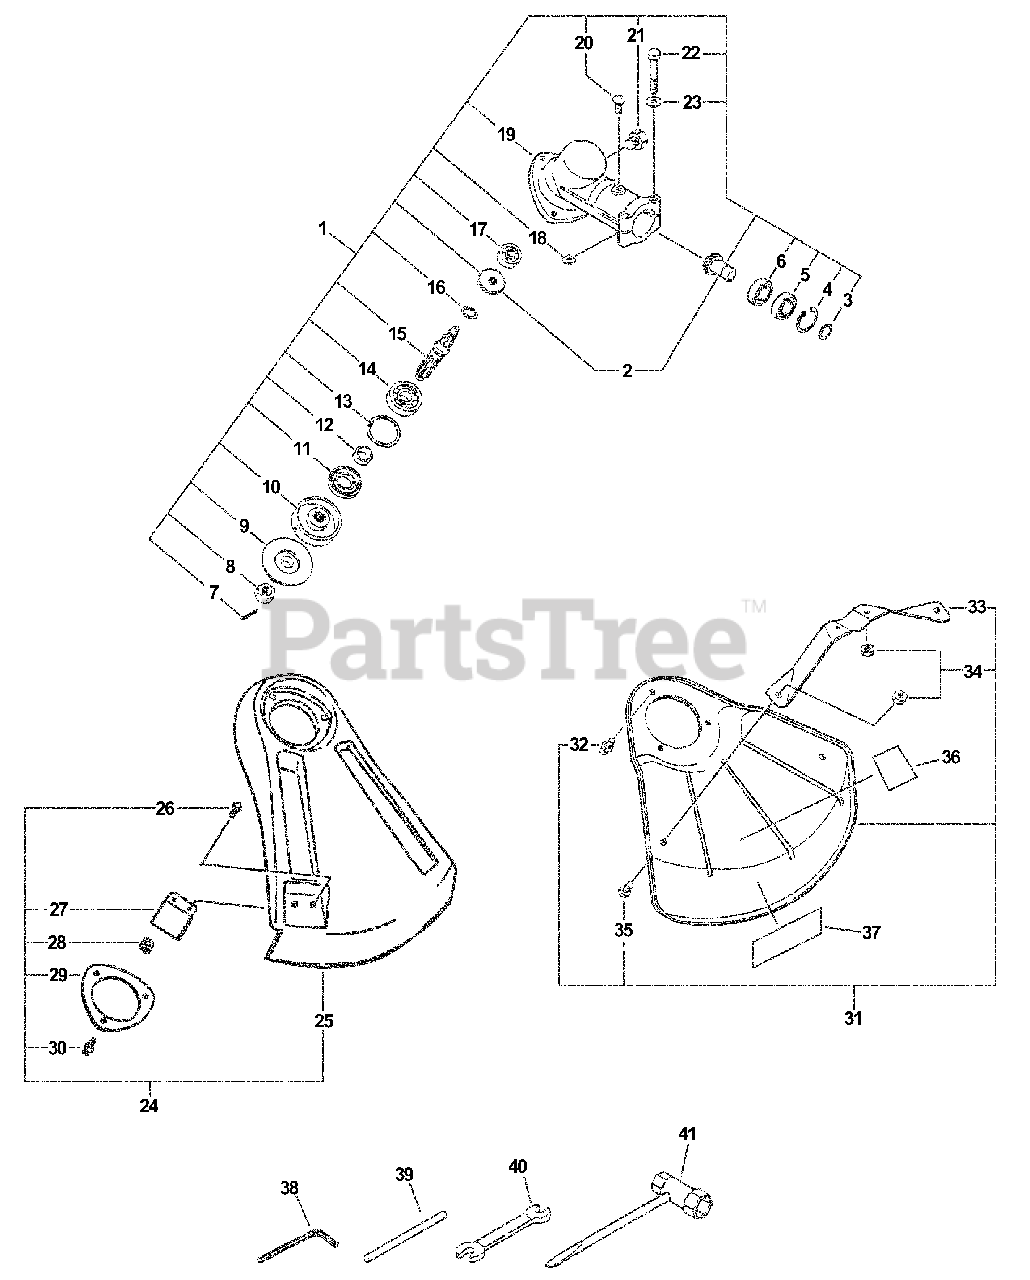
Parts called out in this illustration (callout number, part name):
1	GEAR CASE ASSY
2	GEAR SET
3	RING, RETAINING - 12
4	RING, SNAP 28
5	BEARING, BALL 6001
6	BEARING, BALL 6001
7	PIN, COTTER 2×22
9	PLATE, ADAPTOR - LOWER
10	PLATE, ADAPTER - UPPER
11	SEAL, OIL 22
12	SPACER 11.8×15×9
13	RING, SNAP Ø32
14	BEARING, BALL - 6201 C3
15	SHAFT, GEAR
16	RING, SNAP Ø12
17	BEARING, BALL 6000
19	CASE, GEAR
20	SCREW 5×10
21	BOLT 8×8 SP
22	BOLT 5×40
23	WASHER, FLAT 5.5×10×0.8
24	DEBRIS SHIELD KIT
25	SHIELD, DEBRIS
26	SCREW 5×16
27	CUTTER, LINE
28	NUT M5
29	PLATE, SHIELD Ø49.5 MM
30	SCREW 5×16
31	SHIELD
32	SCREW 5×10
33	BRACKET, SHIELD MOUNTING
34	NUT, LOCK M5
35	SCREW 5×8
36	LABEL, DANGER
37	LABEL, ECHO
38	WRENCH, ALLEN 4 MM
39	TOOL, LOCKING 5×120 MM
40	SPANNER 8×10
41	T-WRENCH 17x-19 L200
